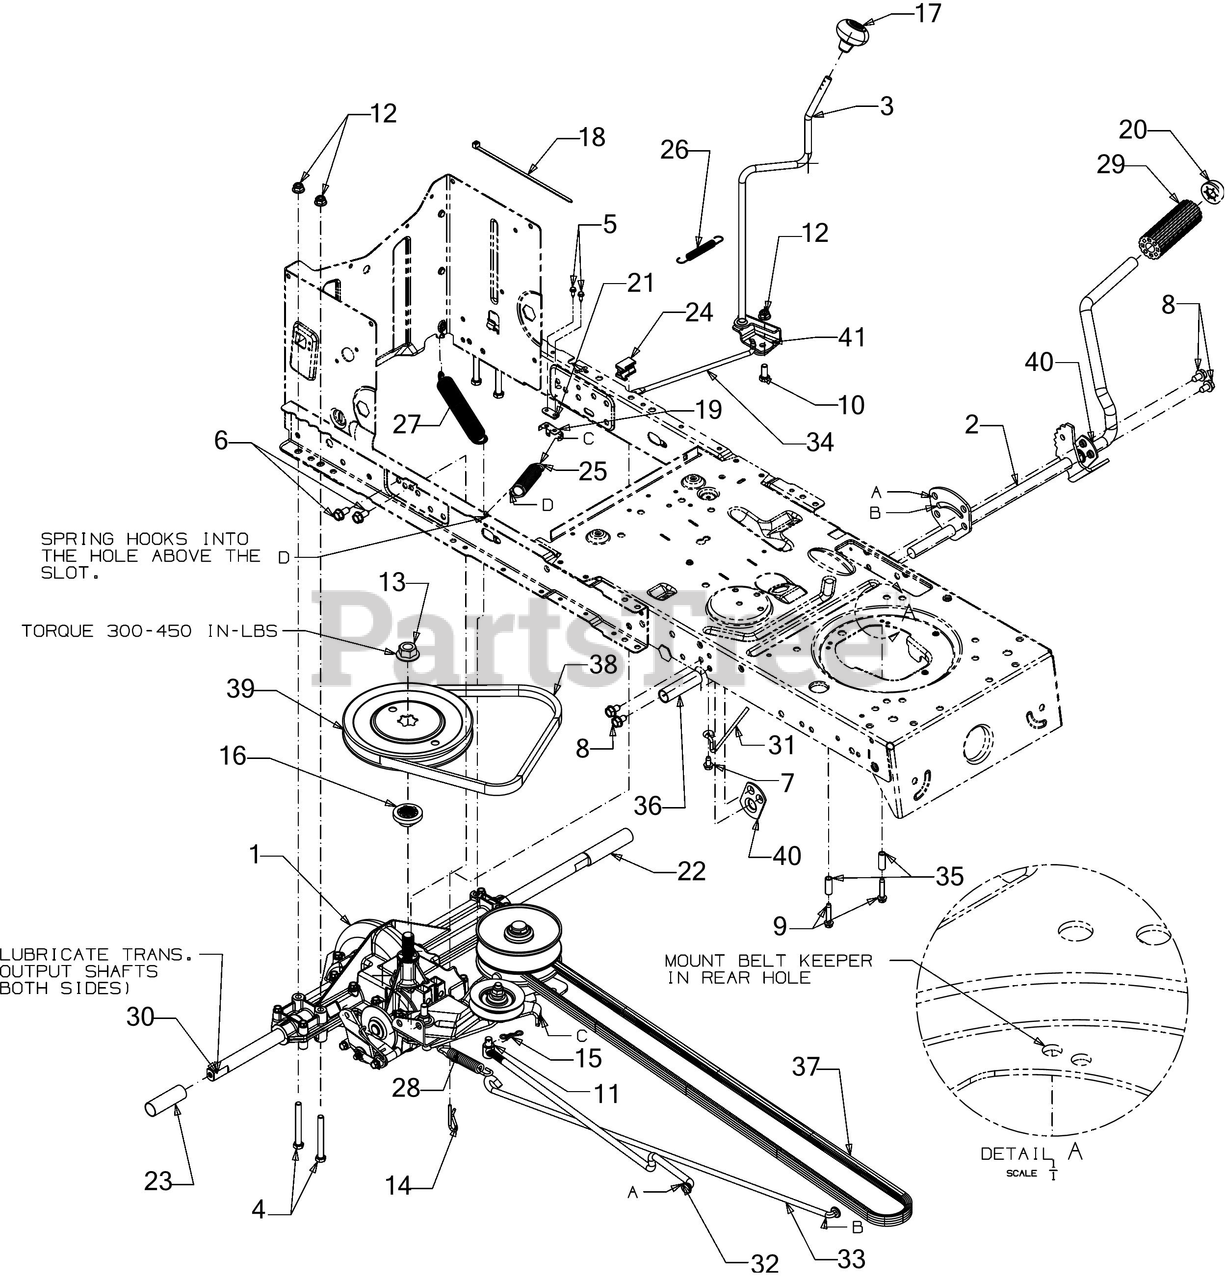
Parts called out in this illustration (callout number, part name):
1	TRANSMISSION DRIVE-SINGLE SPEED
2	PEDAL ASSEMBLY
3	SHIFT LEVER ASSEMBLY
4	HEX SCREW 5/16-18 x 2.75
5	HEX SCREW WASHER HD #8-18 x 0.500
6	SCREW 5/16-18 x .750
7	SCREW 1/4-20 X.500
8	SCREW 5/16-18 x .625
9	SCREW 1/4-20 x 1.25
10	SCREW 5/16-18 x .75 GR5
11	FERRULE 3/8-24 x .375
12	FLANGE LOCK NUT 5/16-18
13	FLANGE NUT W/HUB
14	COTTER PIN
15	BOW TIE COTTER PIN 1/4-5/16
16	PULLEY HUB
17	SHIFT KNOB
18	7" CABLE TIE
19	SAFTEY SPRING SWITCH
20	PUSH CAP
21	INSULATOR PLATE
22	SLEEVE
23	SLEEVE
24	SHIFT ROD BEARING
25	EXTENSION SPRING
26	EXTENSION SPRING .38 OD x 3.25 LG
27	EXTENSION SPRING .94 x 6.75
28	EXTENSION SPRING
29	FOOT PAD
30	GREASE(NOT SERVICEABLE)
31	BELT KEEPER ROD
32	VARIABLE SPEED ROD
33	BRAKE ROD
34	SHIFT ROD
35	SPACER
36	SPACER-5/8 ID x 2.
37	V-BELT 70.90
38	V-BELT 5L x 35.25
39	V- PULLEY W/HUB
40	PEDAL SUPPORT BRACKET
41	SHIFT ADJUSTMENT BRACKET
